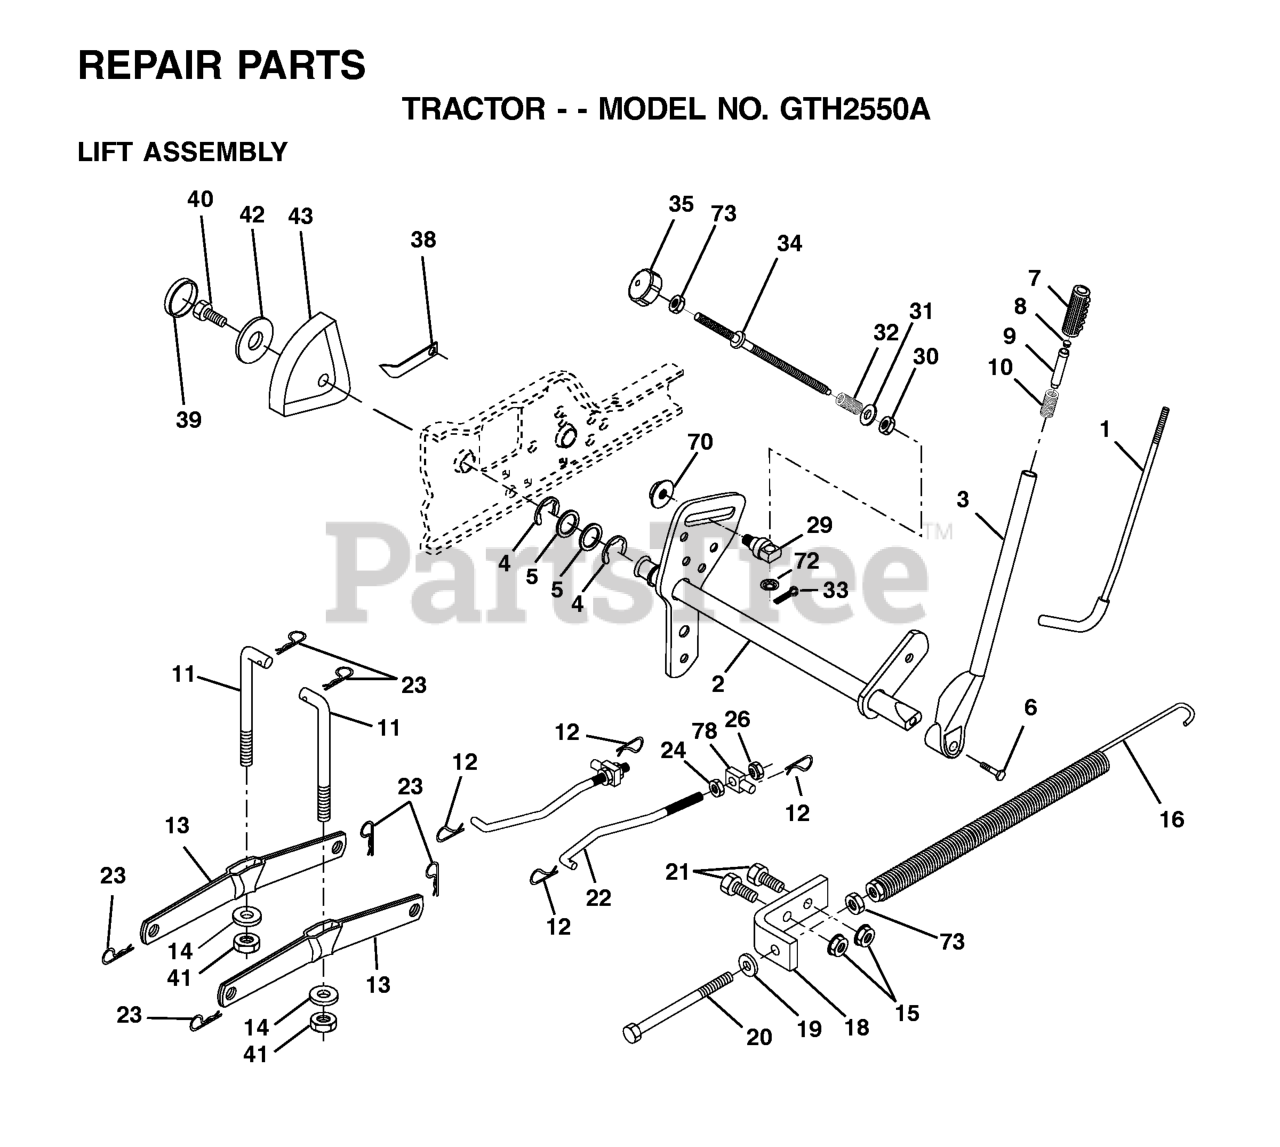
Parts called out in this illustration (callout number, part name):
1	LEVER ROD LT
3	LEVER ASSY-LIFT RH
5	Washer 29/32 x 1 - 1/4 x 16 Ga.
6	Bolt, Fin Hex 3/8-16 x 1-1/12
7	GRIP HANDLE
8	PLUNGER BUT KIT
9	PLUNGER BUT KIT
10	SPRING**
11	LINK LIFT
12	SPRING RETAINER
13	ARM.REAR.SUSPENSION
14	BEARING.PIVOT.LIFT
16	LIFT SPRING
19	WASHER
21	BOLT
22	FRONT LINK
23	RETAINER-SPRNG RB
24	NUT.HEX.JAM.1/2-13
26	NUT.LK.W/WSH.1/2.
32	SPRING.COMP.INF.H
33	COTTER PIN
34	ROD.LIFT.ADJUSTABLE
35	KNOB INF 3/8-16
38	POINTER, HEIGHT INDICATOR(2 2)
40	SCREW 5/16-18X1
41	NUT CROWNLOCK 3/8-24
43	HEIGHT INDICATOR
70	NUT
72	NUT PUSH M
73	NUT
78	TRUNION
